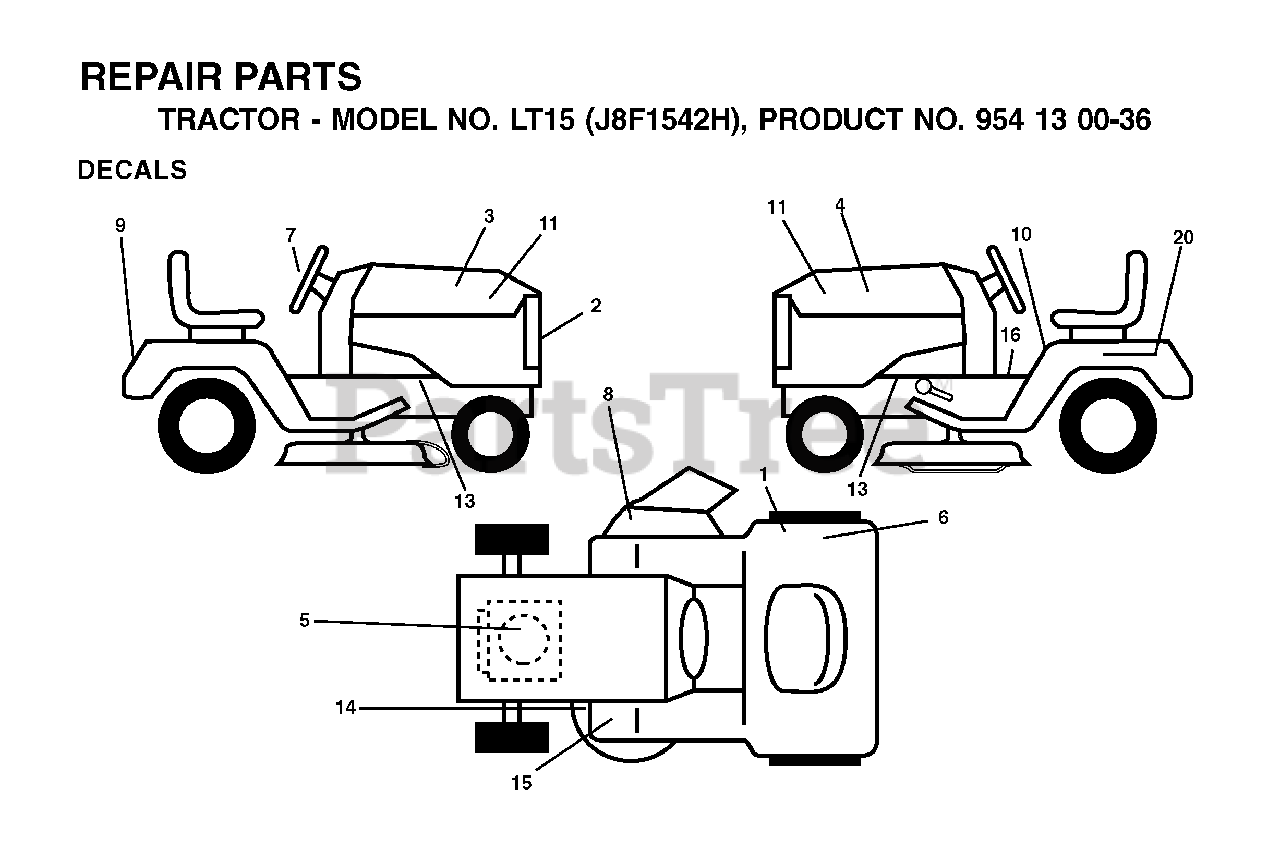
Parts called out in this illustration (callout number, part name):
1	DECAL CERTIFICATION
6	DECAL EUROPE STANDARD CE
8	DECAL MOWER CUT/FINGER
10	DECAL READ OWNER'S MAN SYMS
14	DECAL V BELT SCHEMATIC
16	DECAL PARK BRAKE
20	DECAL BTRY SYMBOLS
